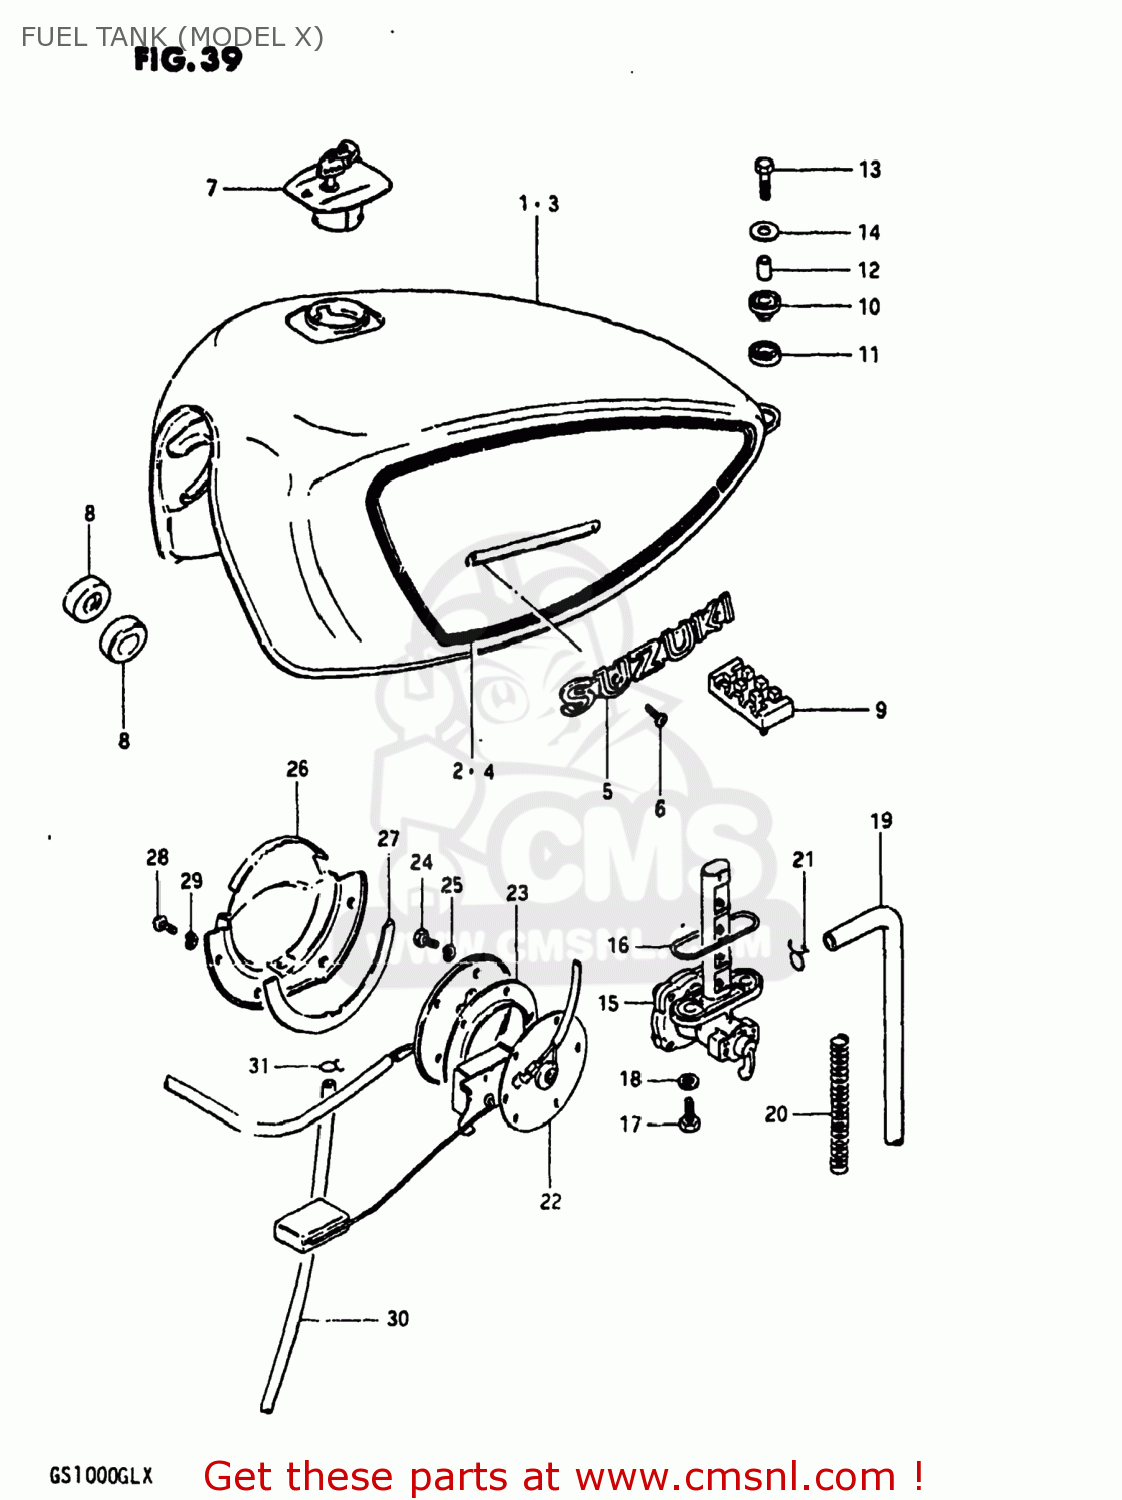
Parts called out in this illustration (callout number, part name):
1	TANK ASSEMBLY,FUEL
2	TAPE SET,FUEL TANK
3	TANK ASSEMBLY,FUEL
4	TAPE SET,FUEL TANK
5	EMBLEM,FUEL TANK
6	SCREW 3X6
7	CAP SET,FUEL TANK
8	CUSHION
9	CUSHION,FUEL TANK CTR
10	CUSHION
11	CUSHION
12	SPACER
13	BOLT
14	WASHER (6.5X24X1.6)
15	COCK ASSEMBLY,FUEL
16	O RING
17	BOLT(6X20)
18	GASKET
19	HOSE
20	SPRING
21	CLIP
22	GAUGE ASSEMBLY,FUEL LEVEL
23	GASKET,FUEL LEVEL GAUGE (NAS)
24	BOLT
25	LOCK WASHER
26	PLATE,FUEL DRAIN
27	GASKET,FUEL DRAIN PLATE (NAS)
28	SCREW
29	LOCK WASHER
30	HOSE
31	CLIP
